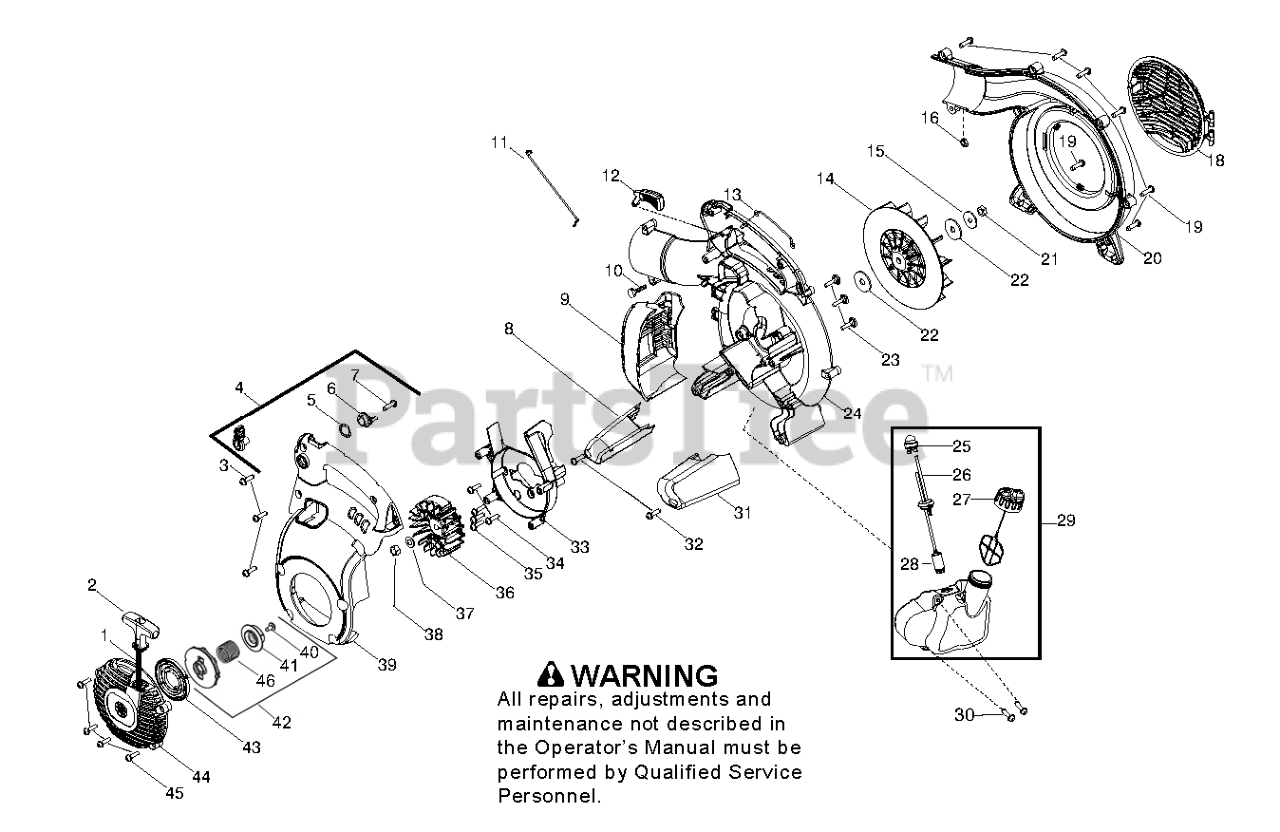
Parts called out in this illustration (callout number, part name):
2	STARTER HANDLE
4	KIT CRUISE CONTROL
5	WAVE WASHER
6	RATCHET CRUISE CONTROL
8	FOOT, FRONT IMPACT
9	ASSY, MUFFLER GUARD
11	WIRE LINKAGE
12	TRIGGER, THROTTLE
13	WIRE, HANDLE GROUND
15	WASHER-FLYWHEEL
18	COVER VAC DOOR
20	ASSEMBLY OUTER SCROLL
21	NUT, IMPELLER
22	WASHER IMPELLER
23	SCREW FUEL TANK RETAINER
24	SCROLL, INNER
26	FUEL LINE GROMMET KIT
28	FUEL PICK-UP ASSY
31	FOOT, REAR IMPACT
33	SCROLL, FLYWHEEL
35	SCREW - SHROUD
36	FLYWHEEL ASSY
37	WASHER FLAT
38	NUT-FLYWHEEL
42	KIT - STARTER
43	SPRING STARTER
44	HOUSING - STARTER COVER
46	SPRING EPS2
